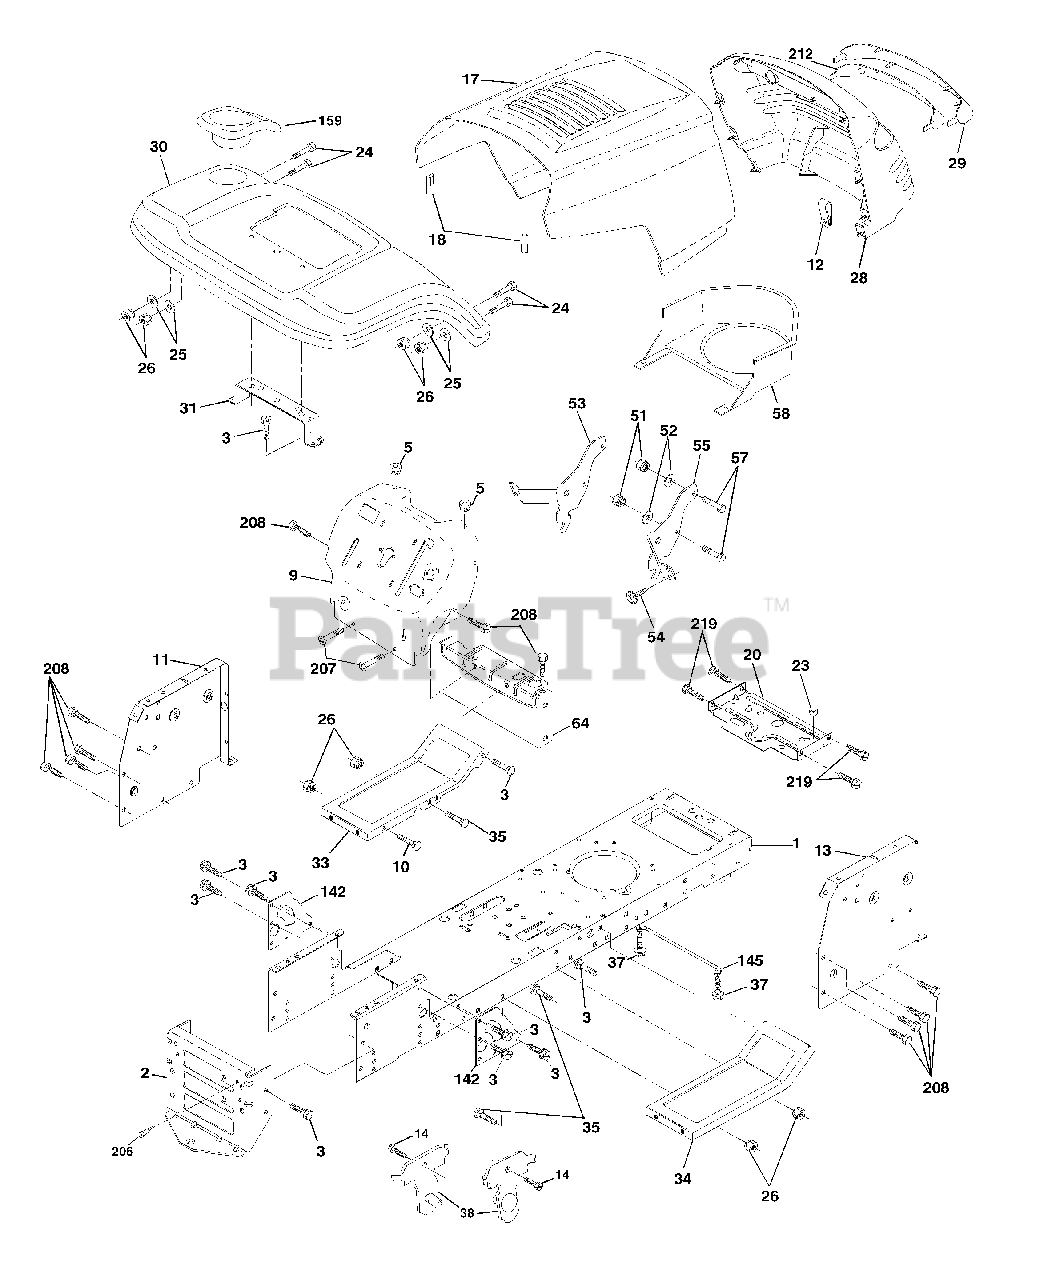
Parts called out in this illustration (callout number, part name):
1	Chassis
2	Drawbar
3	Screw 3/8-16 X .75
5	Bumper Hood/Dash
9	Dash P/L
10	Bolt Carriage 3/8-16 x 1
11	Panel Dash Lh
12	Clip Tinnerman
13	Panel Dash Rh
14	Screw Thdrol 3/8-16 x 1/2
17	Hood LT/PL
18	Bumper Hood
20	Plate Mtg Battery Fuel Tank
23	Bushing
24	Bolt Fin Hex 3/8-16 x 1 Gr 5
25	Washer 13/32 X 13/16 X 12 Ga
26	Nut Lock Hex W/Ins 3/8-16 Unc
28	Grille/Lens Asm
29	Lens LT/PL
30	Fender Footrest STLT Pnt
31	Bracket Fender
33	Footrest Pnt Lh
34	Footrest Pnt Rh
35	Bolt Rdhd Sht Sqnk 3/8-16 x 3/4
37	Screw Thdrol 6/16-18 x 1/2 TYT
38	Bracket Asm Pivot Mower Rear
51	Nut Lock Hex W/Ins 1/4-20
52	Washer 9/32 x 7/8 x 16 Ga.
53	Bracjet Grukke Lh
54	Screw Hex Wshd 8-18 x 7/8
55	Bracket Grille Rh
57	Bolt Hex 1/4-20 x 3/4
58	Duct Air
64	Dash Lower STLT
142	Plate Reinforcement STLT
145	Rod Pivot Chassis/Hood
159	Cupholder
206	Bolt Shoulder 5/16-18
207	Screw Thdrol 5/16-18 x 1/2
208	Screw Thdrol 3/8-16 x 1/2
212	Insert Lens Relect
219	Screw 5/16-18 x 3/4
